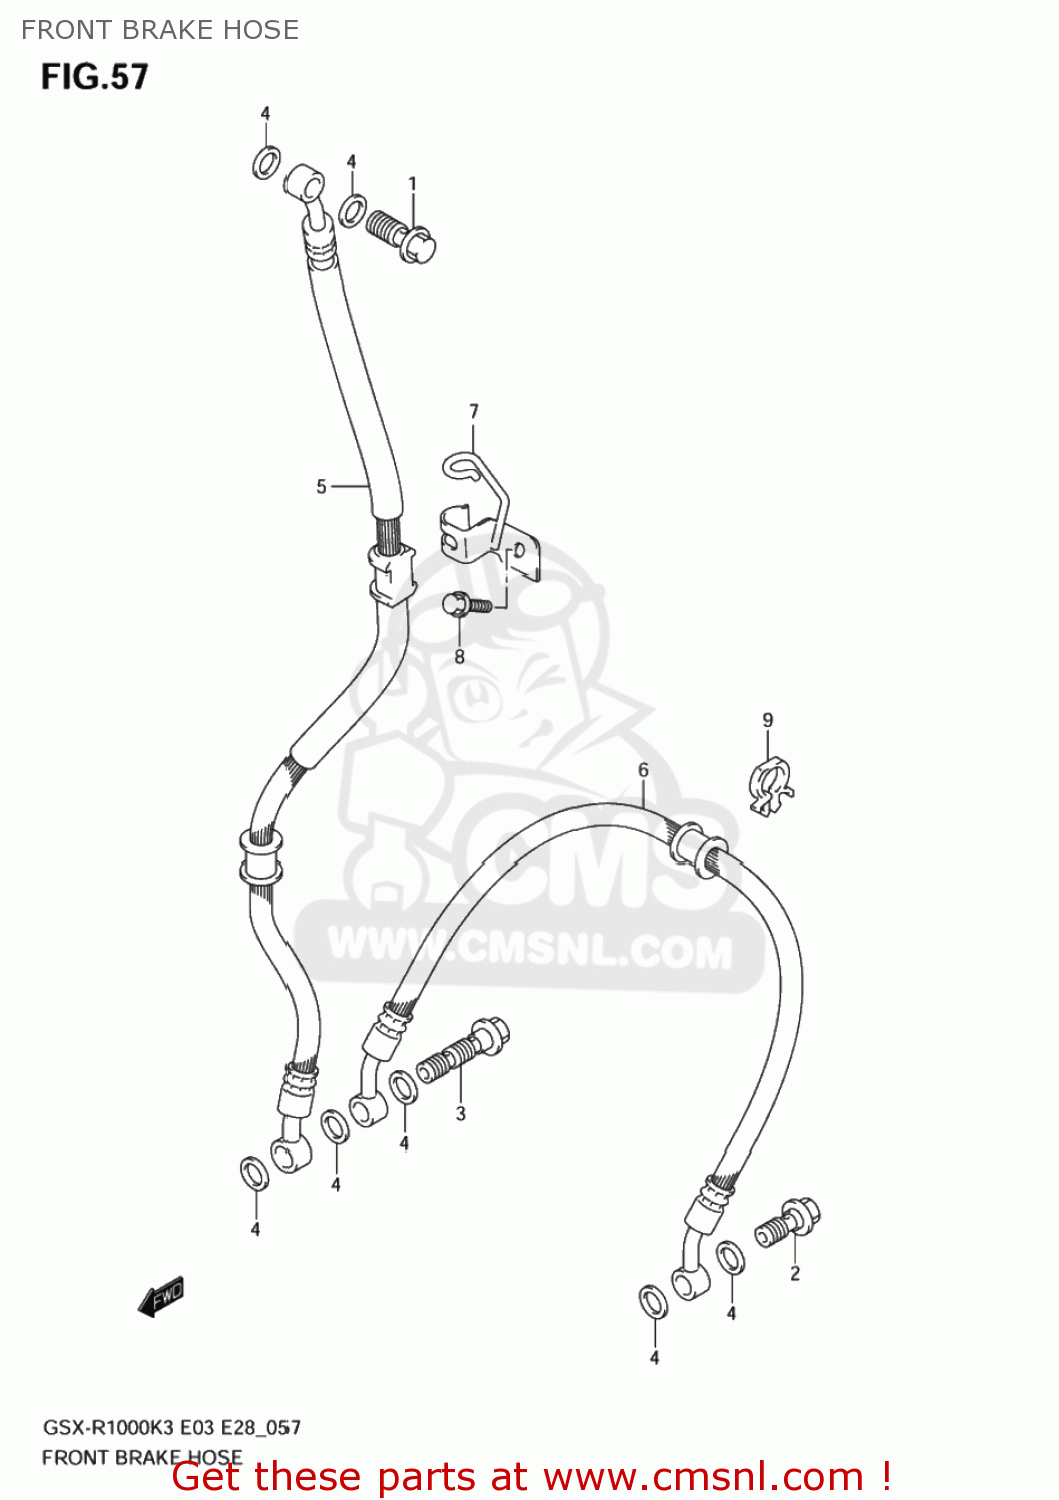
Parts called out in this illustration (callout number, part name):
1	BOLT UNION
2	BOLT UNION
3	BOLT UNION
4	WASHER(10X15X1.5)
5	HOSE,FR BRAKE NO.1
6	HOSE,FRONT BRA
7	CLAMP,FR BRAKE HOSE
8	BOLT
9	CLAMP
